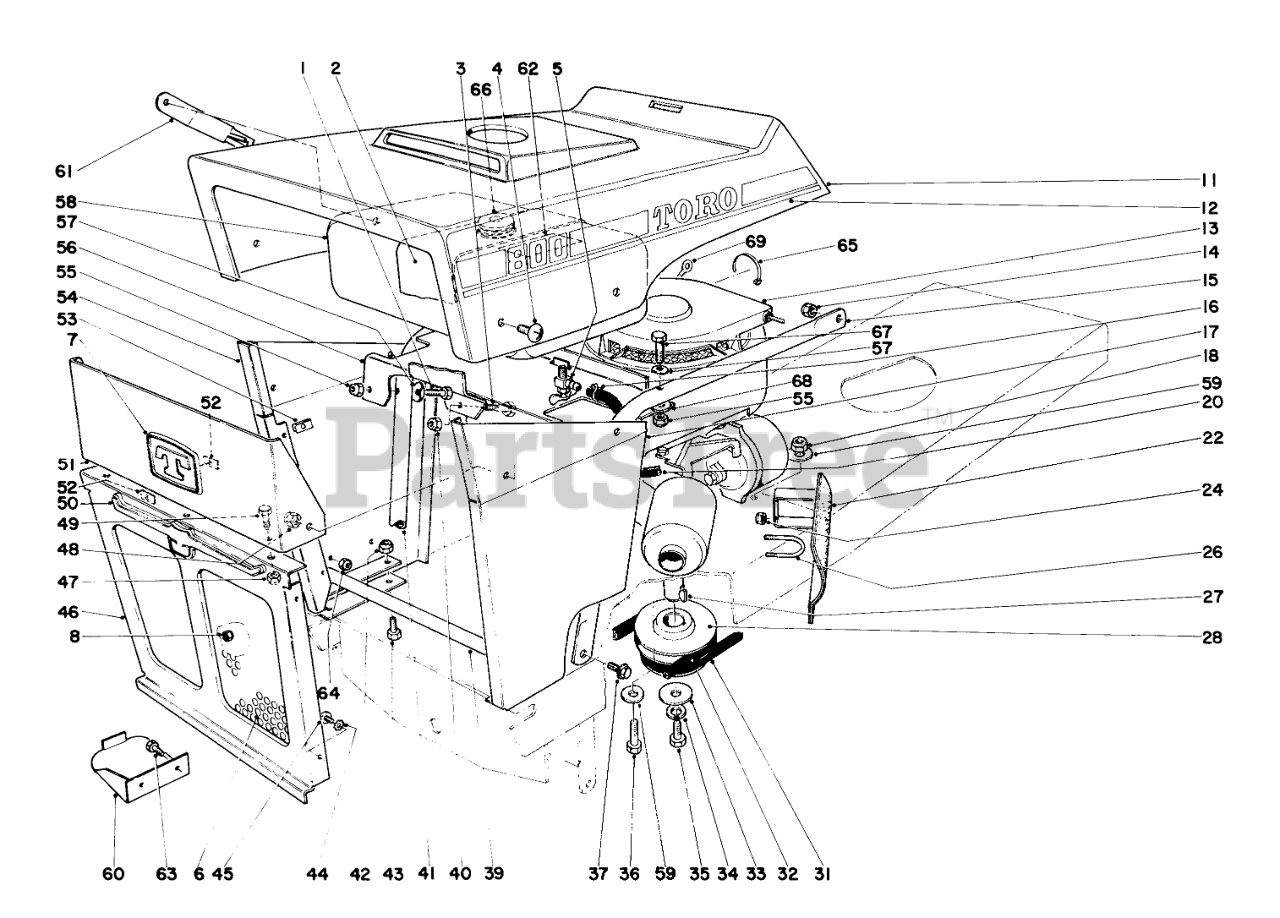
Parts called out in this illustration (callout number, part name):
1	SCREW-HH
2	Strap Gas Tank
3	SCREW-HH
4	Truss Head Screw
5	Hose Fitting
6	Grille Panel
7	Logo Plate Recoil
8	NUT-LOCK, NI
12	Decal Hood Left (Recoil)
13	Engine (Recoil)
15	Support Gas Tank Left
16	CLAMP-HOSE
17	Skin Left Front
18	Nut
22	Muffler Guard
24	NUT-LOCK
26	U-Bolt
27	WoodruffKey
28	Engine Pulley
31	V BELT TRACTION
32	V BELT PTO
33	WASHER-FLAT
34	WASHER-LOCK
35	SCREW-HH
36	SCREW-HH
39	Hinge
41	Support Gas Tank Right
43	SCREW-HH
44	WASHER-LOCK, EXT
46	Grille
48	Nut
49	SCREW-HH
50	Bullshead
51	Blank Headlamp (Recoil)
52	Tinnerman Nut
53	NUT-CLIP,U
54	Skin Right Front (Recoil)
56	Bracket Gas Tank
57	WASHER
58	Gas Tank
59	WASHER-PLAIN
60	Trimmer Support
61	Bracket Trimmer
62	Decal
63	SCREW-HH
64	NUT-LOCK, CONE
65	CONTROL WIRE CLIP
66	Gage-Fuel
67	SCREW-HH
68	Spacer
